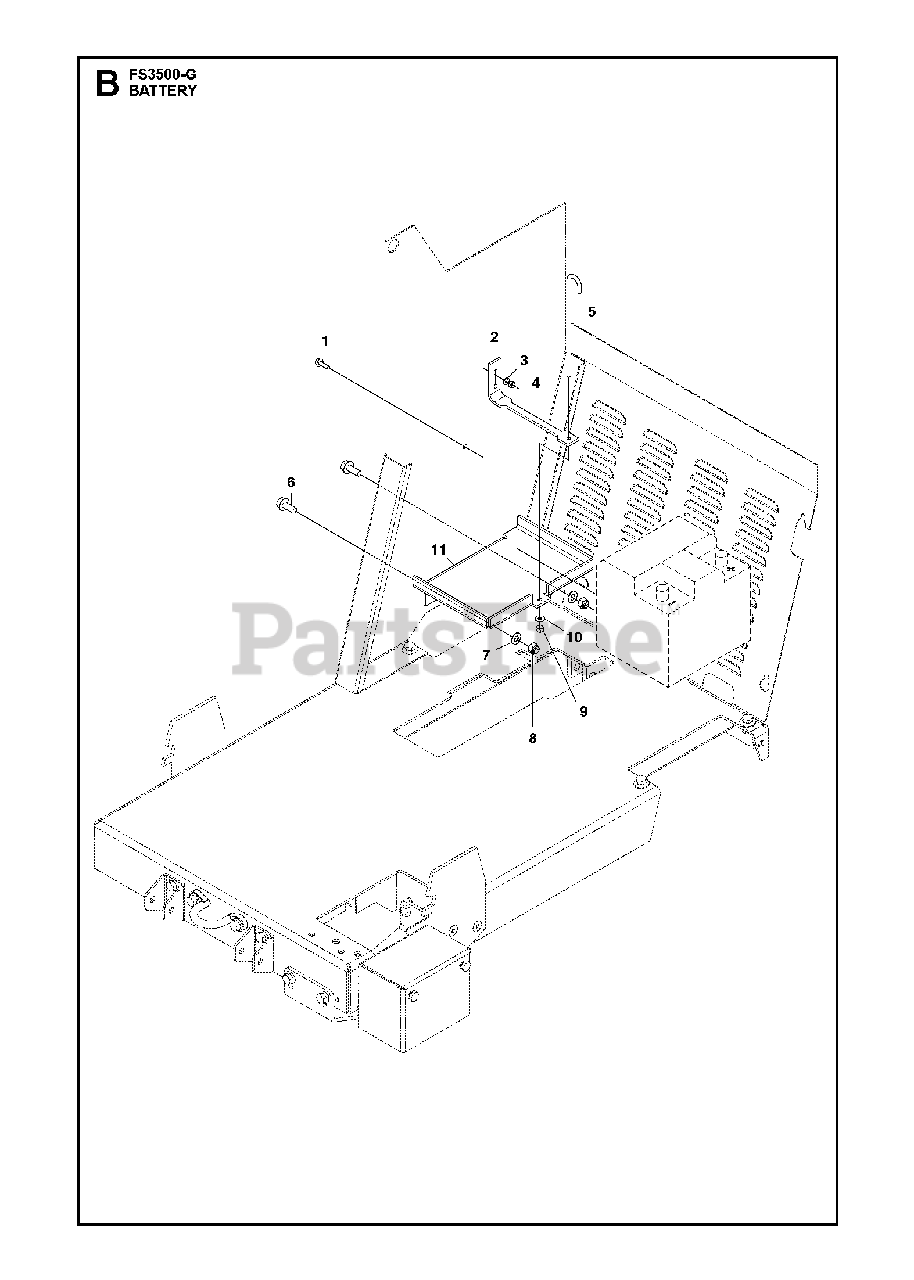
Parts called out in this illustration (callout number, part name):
4	HEXAGON LOCKING NUT
7	WASHER
8	HEXAGON LOCKING NUT
9	NUT
10	WASHER 1/4 SAE
